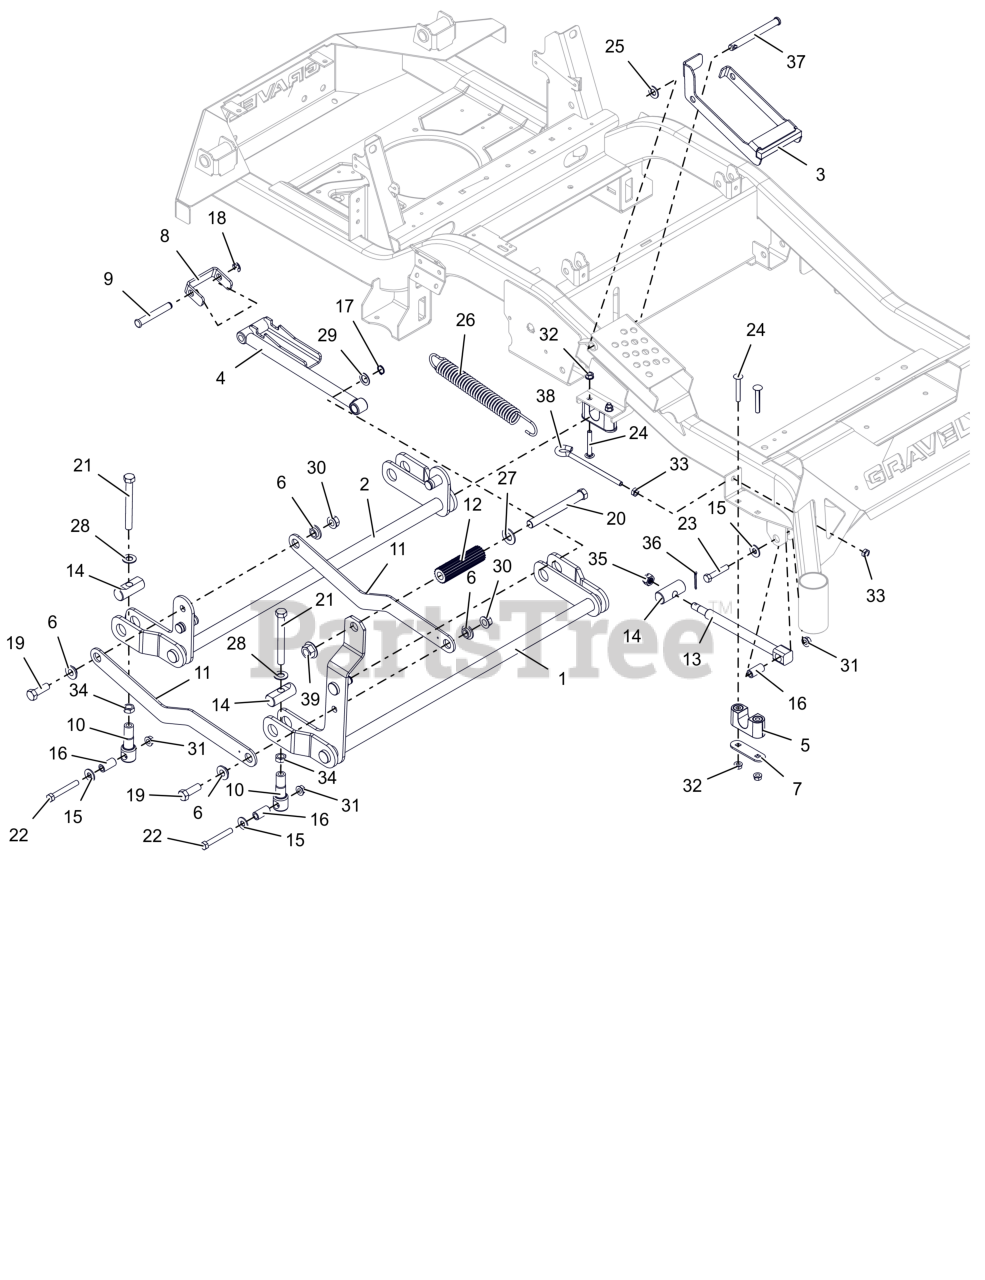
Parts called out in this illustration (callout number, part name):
1	WLDMT, FRONT DECK LIFT PIVOT
2	WLDMT, REAR DECK LIFT PIVOT
3	WLDMT, HOC TRANSFER LOCK (BLACK)
4	WLDMT, HOC LIFT ARM (BLACK)
5	ASM-BUSHING, DECK LIFT
6	BSHG-FLG .515X.750X.310X1.120
7	PLATE, BEARING SUPPORT
8	BRKT, HOC LINE
9	PIN, .499/.494 x 3.385 CLEVIS
10	LINK, DECK LIFT FORMED
11	LINK, DECK
12	ROD, FOOT PEDAL (BLACK)
13	DRAG,LINK-HD
14	PIN, DECK LIFT
15	WSHR,FLT .438X1.00X.083 ZCC
16	SPACER, DECK LEVELING
17	RG-RTNG-EXT .625X.050
18	RG-RTNG-EXT .500X.042 (E)
19	BLT,HEX .50-13X1.50 G5 ZCC
20	BLT, HEX .62-11X5.50 G5 FBP
21	BLT, HEX .50-13X4.50F G8 ZCC
22	BLT, HEX .38-16X2.75 G8 ZCC
23	BLT,HEX .38-16X2.00 G5 ZCC
24	BLT, RHSSN.31-18X2.25 G5 ZCC
25	WSHR-FL-NYL .518X1.000X.080
26	SG-TENS .162X1.25X8.25 WLD 25
27	WSHRFLT 5/8SAE CARBHARD FBP
28	WSHR, FLT .557X1.040X.102 ZCC
29	WSHR, FLT .630X1.005X.062 ZCC
30	NUT-LK-TOP-FLG .500-13 GF ZCC
31	NUT-LK-TOP-FLG .38-16 ZC120
32	NUT,LK-CTR-FLG .31-18 GF ZCC
33	NUT-JAM .375-16 G2 ZCC
34	NUT-JAM .500-13 G2 ZCC
35	NUT-SL .50-13
36	PIN,CTR.12X1.25EXTPRSQCT ZC120
37	PIN, SLIC-.500X4.97X4.55 -ZC
38	BOLT,.38-16 X 5.25-.62 DIA EYE
39	NUT,FLG-TOP LK .625-11 FBP
